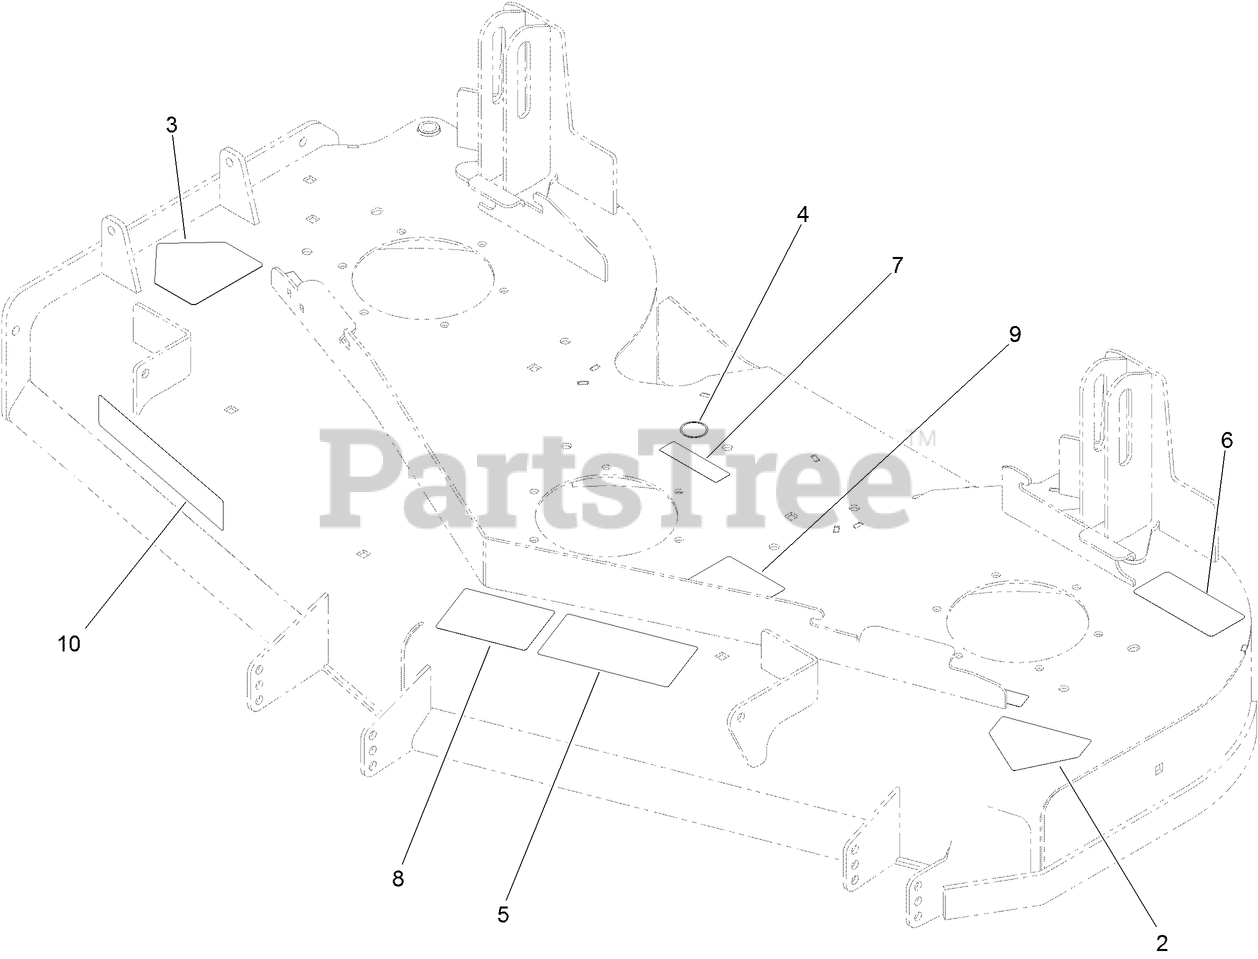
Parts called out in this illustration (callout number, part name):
2	DECAL-DANGER
3	DECAL-DANGER
4	DECAL-GREASE
5	DECAL-DANGER, THROWN OBJECT
6	DECAL-TORQUE
7	DECAL-COVER, MISSING
8	DECAL-SCALP, ANTI
9	DECAL-ROUTING, DECK BELT
